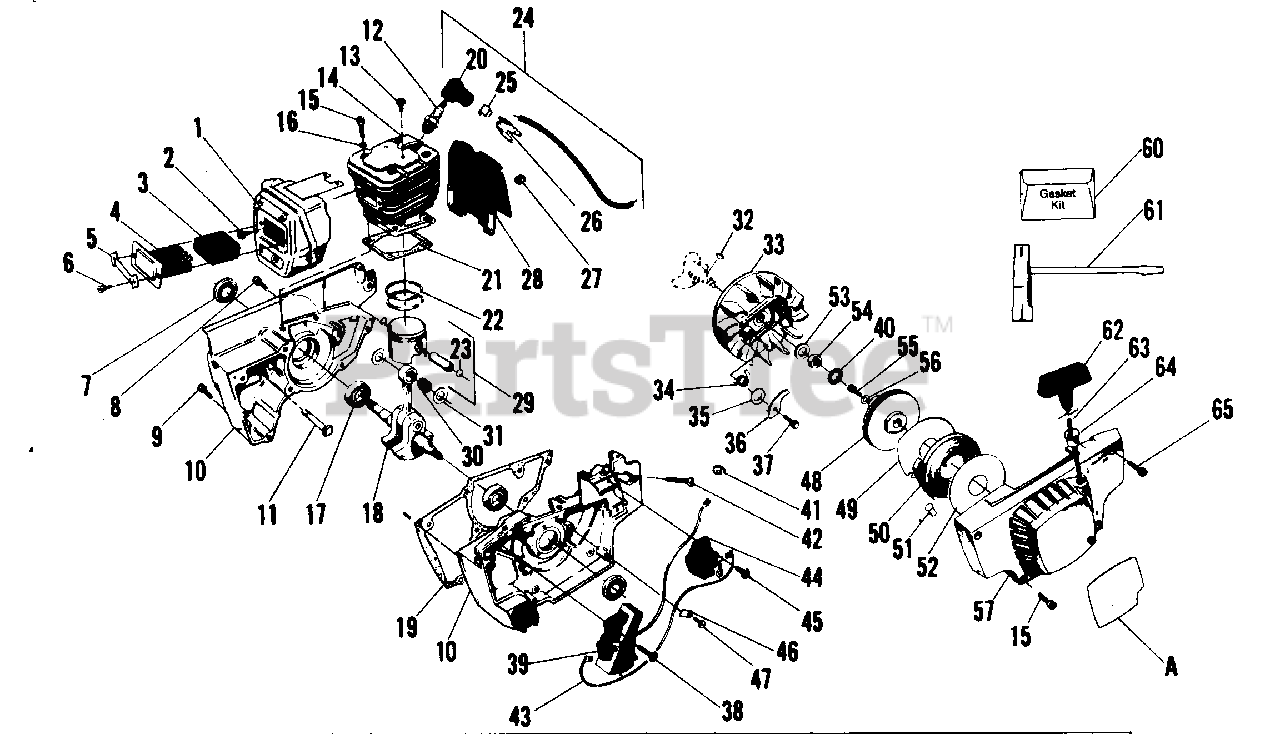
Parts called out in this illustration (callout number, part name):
1	Body Muffler
2	Screw - Muffler (12 - 24 x 5/8)
3	Screen Spark Arrestor
4	Diffuser - Muffler
5	Retainer - Diffuser Mounting Screw
6	Screw - 10 - 32 x 1/2
7	Seal - Crankshaft
8	Screw - Crankcase (#10 - 24 x 3/4 Socket Head)
9	Screw - 8 x 1/2 Socket Head
10	Crankcase Ass'y. (Incl. 10 & 11)
11	Stud - Bar Mounting
12	Spark Plug (CJ - 4)
13	Screw - Muffler Body Bracket Hex Hd. 10 - 24 x 7/16
14	Cylinder
15	Screw - 1/4 - 20 x 1 Socket Hd.
16	Lockwasher - Cylinder
17	Bearing - Crankshaft
18	Crankshaft & Connecting Rod
19	Gasket Crankcase
20	Boot - Spark Plug
21	Gasket - Cylinder
22	Piston Rings
23	Retainer - Piston Pin
24	High Tension Lead Ass'y. (Incl. 20 & 25)
25	Connector - Spark Plug
26	Clip - High Tension Lead
27	Grommet - High Tension Lead
28	Air Baffle Ass'y.
29	Piston Ass'y.
30	Bearing - Piston Rod
31	Washer - Thrust
32	Key - Flywheel
33	Flywheel
34	Spring - Starter Dog
35	Washer - Starter Dog
36	Dog - Starter
37	Stud - Starter Dog
38	Screw - 10 - 24 x 7/8
39	Module - Ignition (Incl. 41 & 43)
40	Seal - Foam - Starter Pulley
41	Grommet - Lead Wire
42	Screw - Idle Speed
43	Lead Wire - Module to Transformer
44	Transformer Ass'y. (Incl. 24)
45	Screw - 10 - 24 x 3/4 Hex Washer Hd.
46	Clamp - Lead Wire
47	Screw - 8 - 32 x 5/16 Tapping
48	Pulley - Starter
49	Disc. - Starter (Over Spring)
50	Spring - Starter Rewind
51	Pin - Spring Anchor
52	Disc. - Starter (Under Spring)
53	Washer - 3/8
54	Locknut - Flywheel - 3/4 - 24
55	Screw - 1/4 - 20 x 1/2 Socket Hd.
56	Washer - Starter Pulley
57	Fan Housing Ass'y.
60	Gasket Repair Kit (Inc. 19,21,27,40)
62	Handle Starter
63	Rope Kit
64	Bushing - Rope
65	Screw - 1/4 - 20 x 1 - 1/2 1/8 Socket Hd.
A	Decal - Fan Housing
